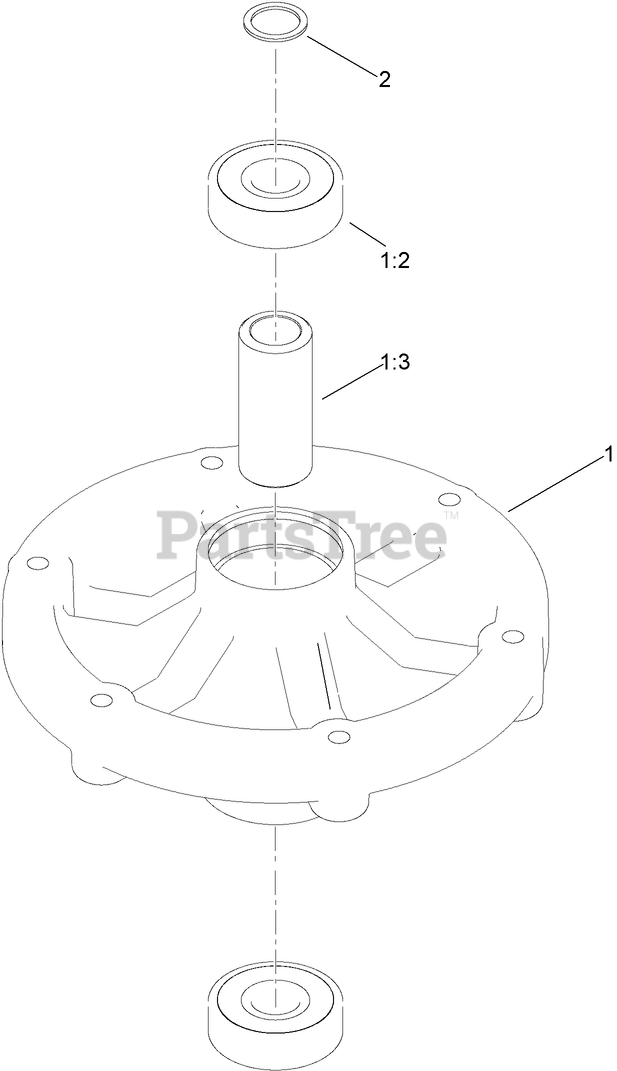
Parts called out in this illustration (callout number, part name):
1	HOUSING-CUTTER
1:2	BEARING
1:3	SPACER-BEARING
2	WASHER-THRUST
